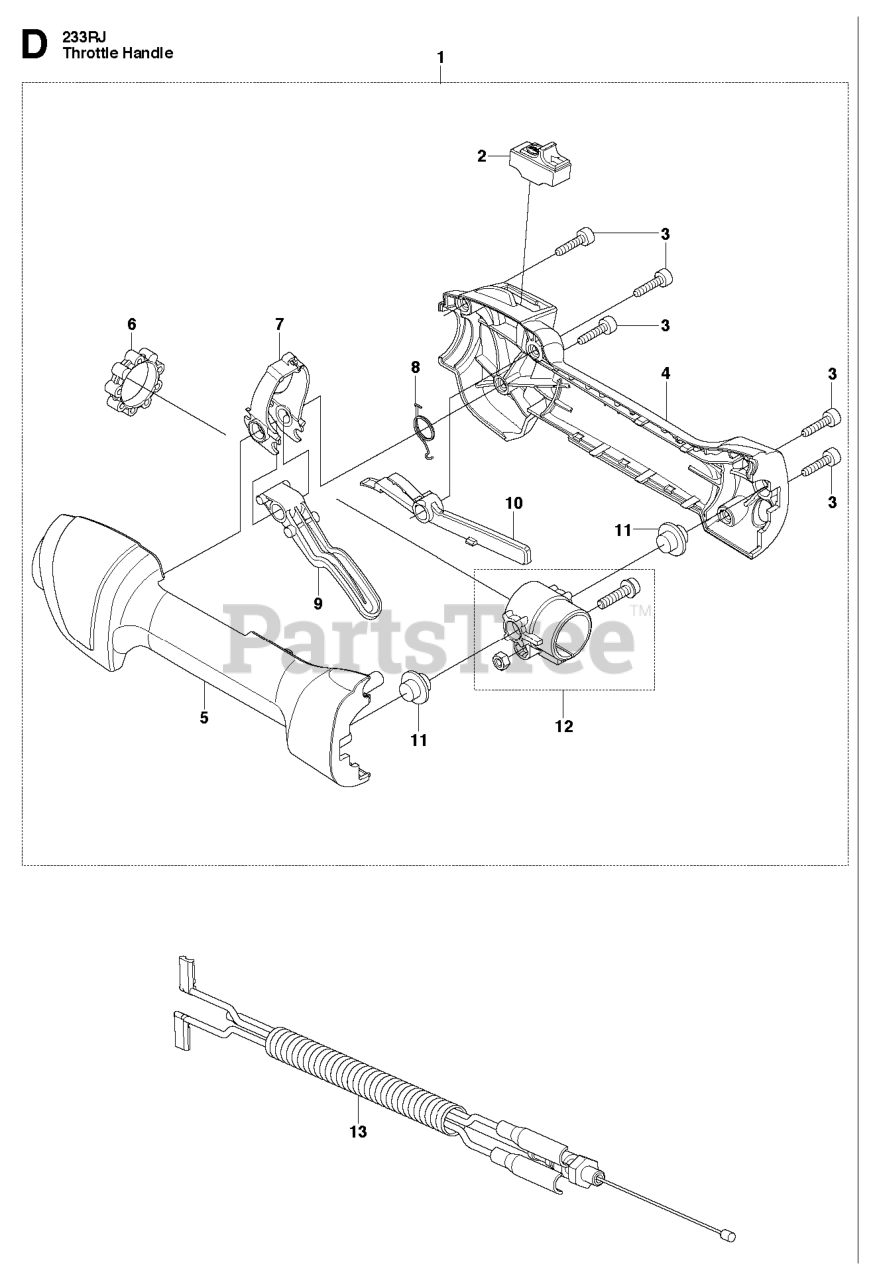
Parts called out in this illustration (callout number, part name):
2	START/STOP SWITCH
6	VIBRATION DAMPER
8	RETURN SPRING
9	THROTTLE TRIGGER
10	THROTTLE LOCK
